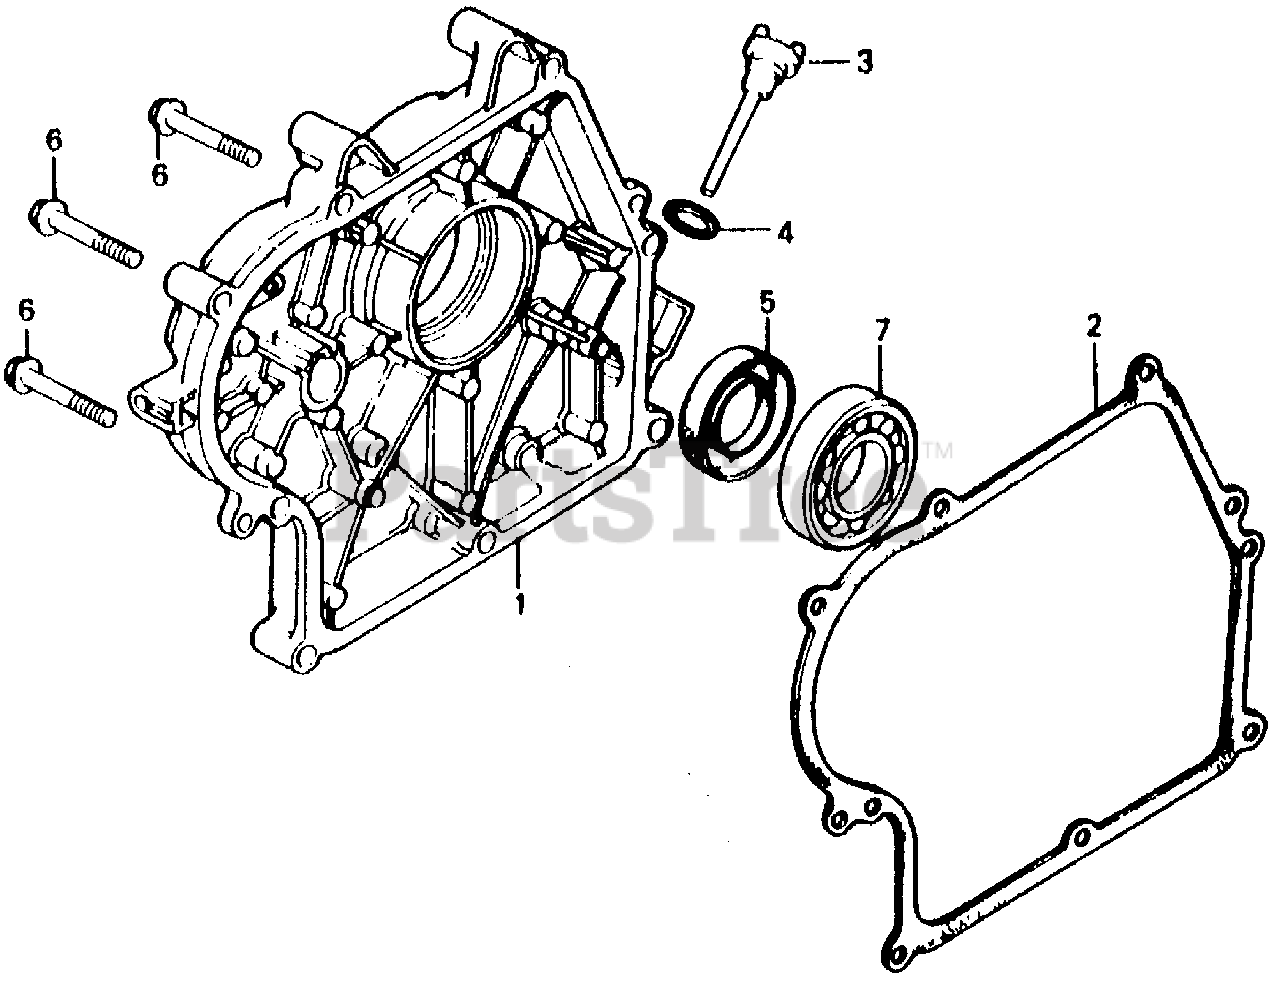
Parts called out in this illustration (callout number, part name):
1	COVER, CRANKCASE
2	GASKET, CASE COVER
3	CAP, OIL FILLER
4	GASKET, OIL FILLER CAP
5	OIL SEAL (30X46X8)
6	BOLT, FLANGE (8X40)
7	BEARING, RADIAL BALL (6206)
